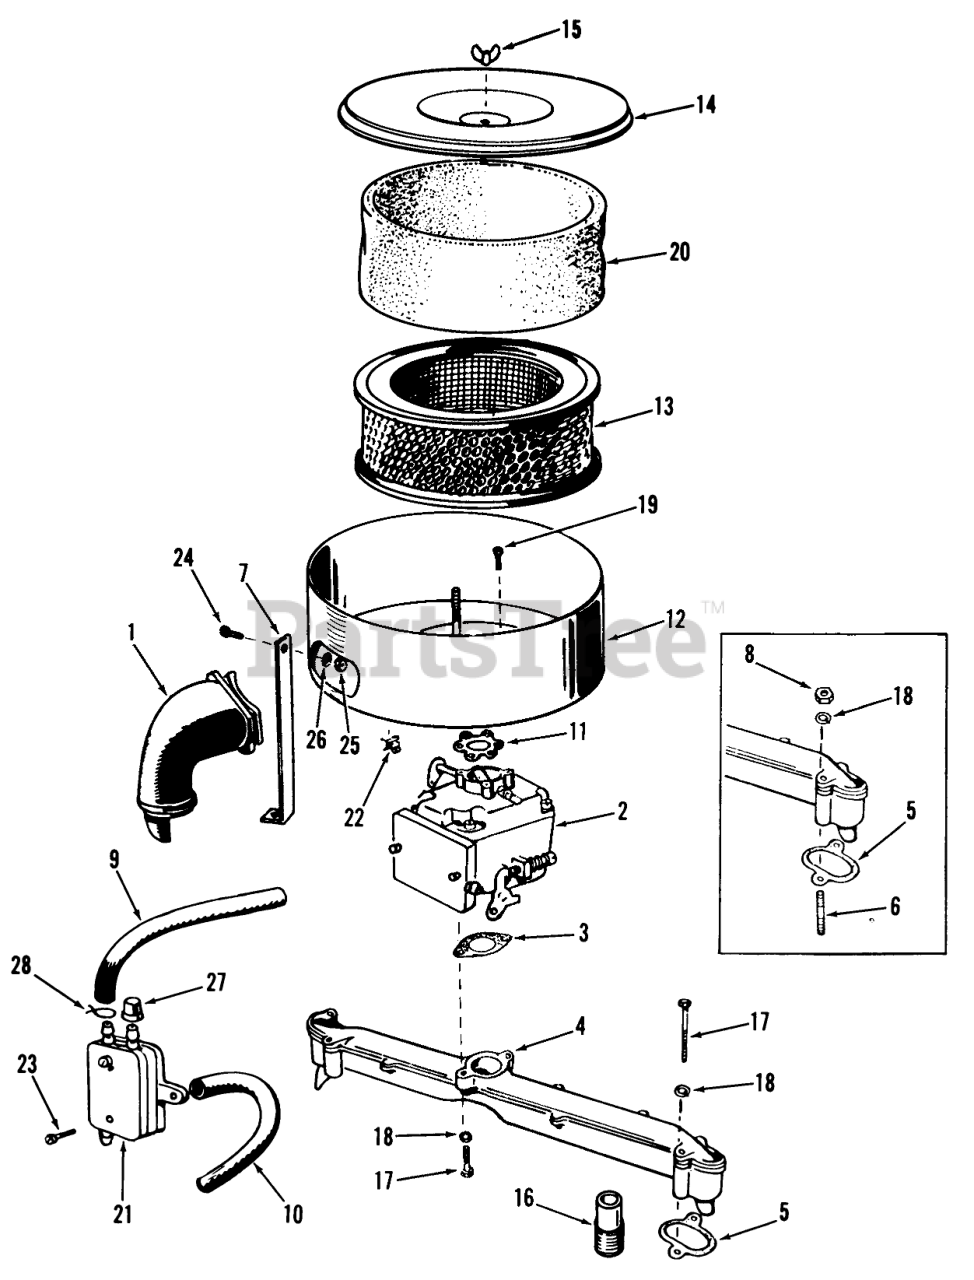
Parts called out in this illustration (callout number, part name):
1	Air Intake Tube
2	Carburetor
3	Carburetor Mounting Gasket
4	Intake Manifold
5	Gasket, Intake
6	Stud-Intake Manifold
7	Air Cleaner Support
8	Nut-Intake Manifold
9	Hose-Fuel Pump To Carburetor
10	Hose-Fuel Pump Vacuum
11	Gasket, Air Cleaner Mounting
12	Air Cleaner Housing
13	ELEMENT-AIR CLEANER
14	COVER-AIR CLEANER
15	Wing Nut-Air Cleaner Cover
16	Nipple, (1" x 2 1/2")-Exhaust
17	Hex Bolt-Intake Manifold Mounting
17	Hex Bolt-Carburetor Mounting
18	Intake Manifold Mounting (5/16")
18	Carburetor Mounting (1/4")
19	SCREW-RD HD10-32X3/8
20	WRAPPER-AIR CLEAN EL
21	Fuel Pump
22	CLIP-BRKT CHOKE CAB
23	Sheet Metal Screw-Fuel Pump
24	Hex Bolt 1/4-20 X 1/2
25	Hex Nut 1/4-20
26	Lockwasher
27	Fuel Pump Cap
28	Clamp, Hose (7/16")
